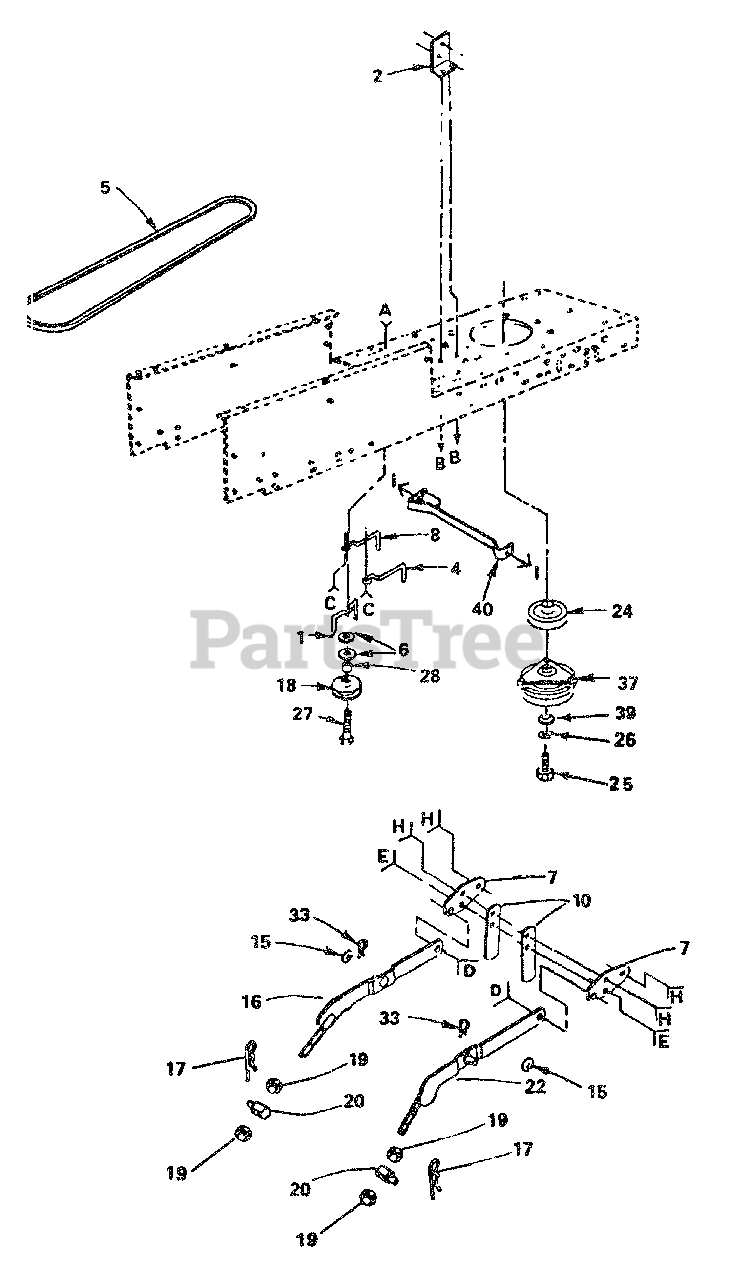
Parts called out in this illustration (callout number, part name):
1	Retainer Belt
2	Bracket-Switch
4	Keeper-Belt, Engine
5	V-Belt, Drive
6	Washer 13/32 x 13/16 x 16 Ga.
7	Bracket-Suspension
8	Keeper, Belt Engine
10	Upstop, Mower
15	Washer 17/32 x 15/16 x 16 Ga.
16	Arm Assembly-Suspension-L.H.
17	Retainer-Spring
18	Idler-Flat
19	Nut-Hex 1/2-13
20	Trunnion-Lift Lower
22	Arm Assembly-Suspension-R.H.
24	Pulley-Engine
25	Bolt-Hex 7/16-20 x 4
26	Washer-Lock 7/18
27	Bolt-Hex 3/8-16 x 2-3/4
28	Spacer
33	Spring-Retainer
37	Clutch-Electric
39	Washer 1-1/2 x 15/32 x 1/4
40	Locater-Clutch
